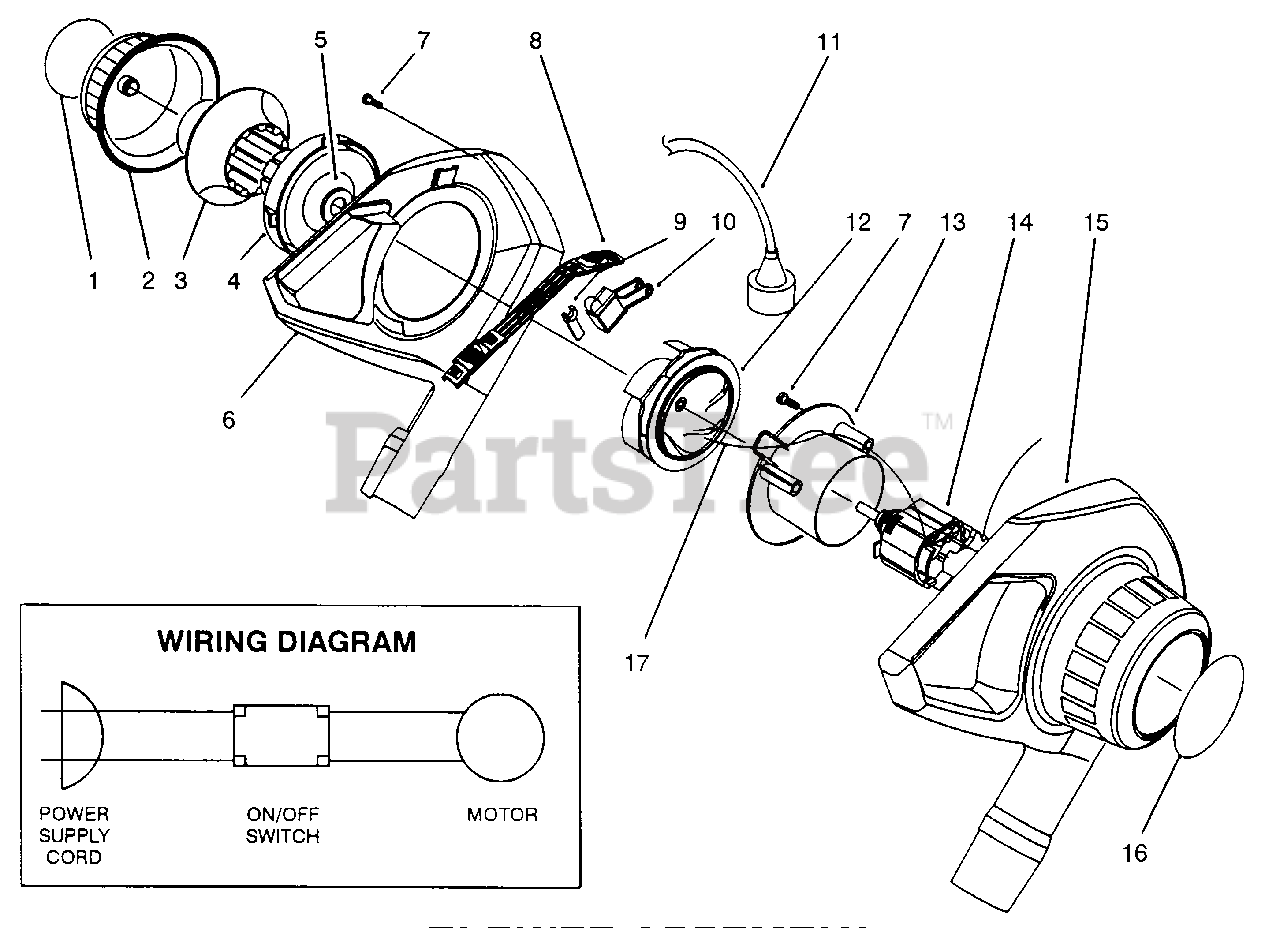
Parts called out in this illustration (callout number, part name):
1	Decal-Choke
2	Cover-Choke
3	Ring-Choke
4	Base-Choke
5	Clip-Retainer
6	Housing Assembly-R.H.
7	Screw
8	Bar-Switch
9	Lever-Actuating
11	Cord-Power
12	Impeller Assembly
13	Plate-Retaining
14	Motor
15	Housing-L.H.
16	Decal-Motor Cover
